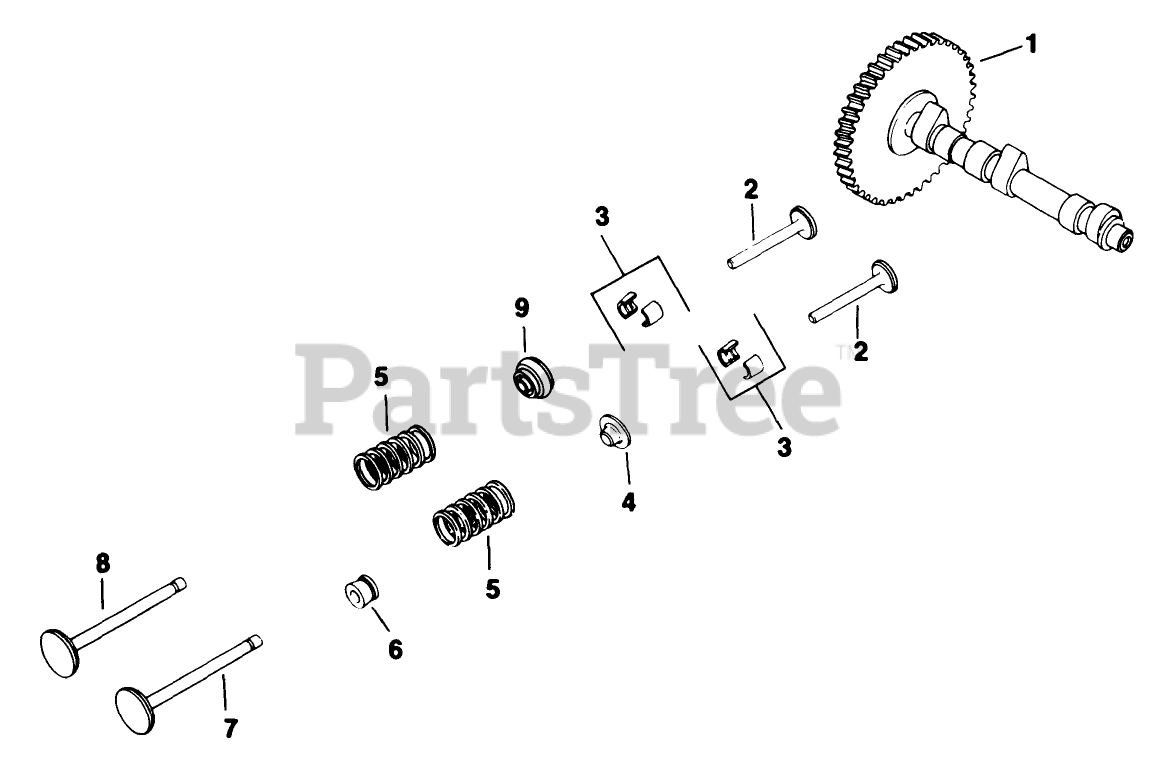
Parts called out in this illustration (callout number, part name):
1	Camshaft
3	Kit-Retainer
4	Retainer-Spring
5	Spring-Valve
6	Seal-Valve Stem
7	Valve-Intake
8	Valve-Exhaust
9	Rotator
